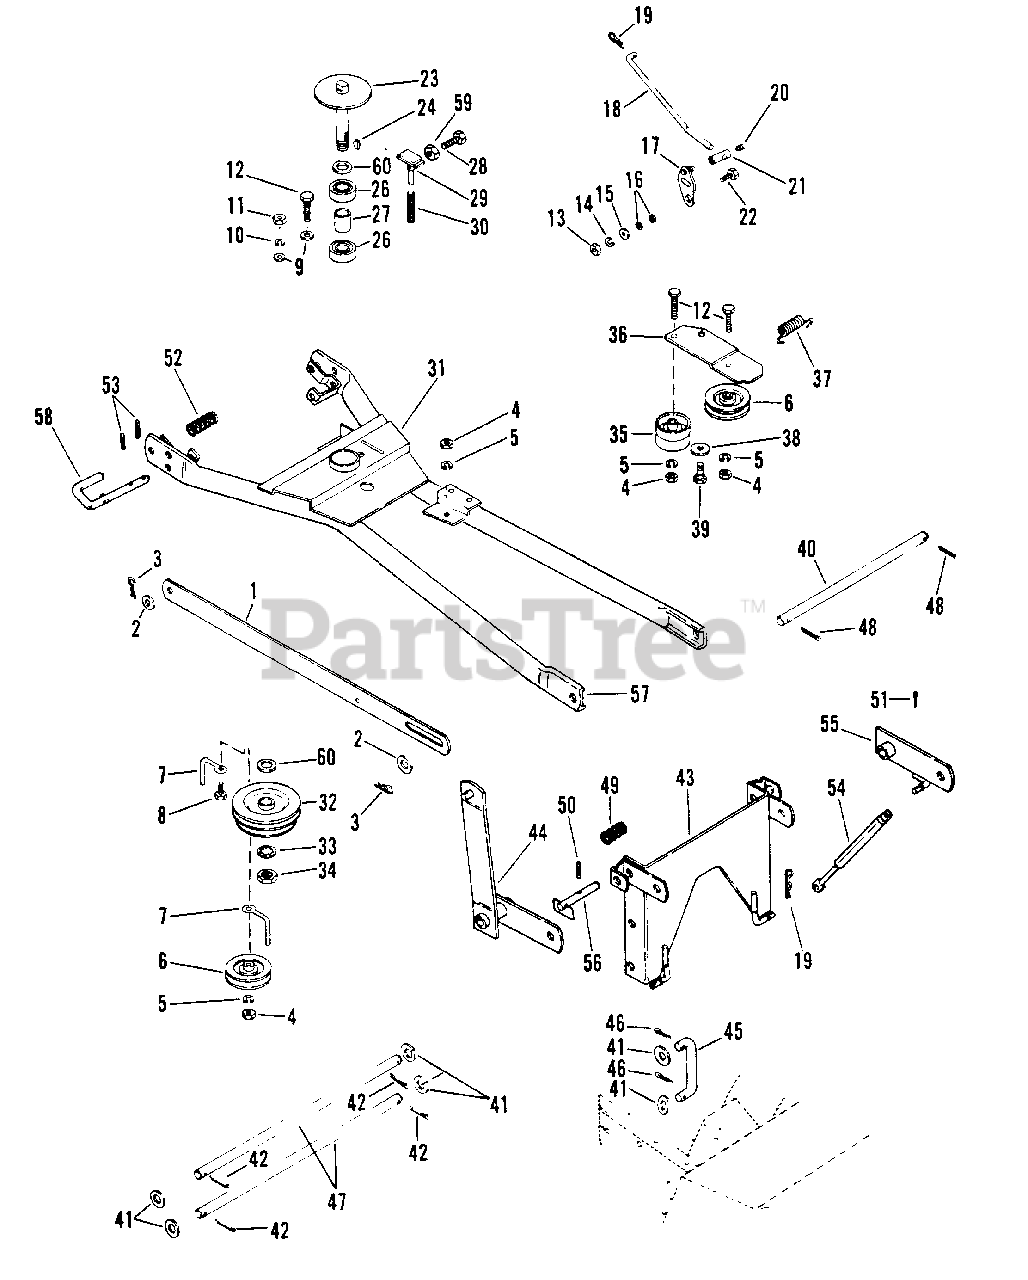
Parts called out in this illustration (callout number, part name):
1	Strap, Lift
2	Washer, Flat .500x1.250x.083
3	Pin, Hair
4	Nut, Hex 3/8-16
5	Washer, Lock 3/8 Reg.
6	Idler, Main
7	Finger, Belt
8	Bolt, Hex 5/16-18x1.00
9	Washer, Flat .406x.812x.065
10	Washer, Lock 5/16 SP
11	Nut, Hex 5/16-18
12	Bolt, Hex 3/8-16x1.75
13	Nut, Hex 1/4-20
14	Washer, Lock
15	Washer, .312x.734x.065
16	Washer, Flat .250x.500x.049
17	Actuator, Brake
18	Rod, Brake
19	Pin, Hair Int. 3/32
20	Set Screw, 5/16-18x.375 HSCP
21	Adaptor, Rod
22	Bolt, Hex 1/4-20x.750
23	Shaft, Spindle
24	Key, Woodruff .187x.75x#9
26	Bearing, Radial
27	Spacer
28	Screw, Cap 10-24x1.25
29	Plunger, Brake
30	Spring, Comp.
31	Housing, Spindle
32	Sheave, Double
33	Lockwasher, Internal 3/4
34	Nut, Jam 3/4-10 Hex
35	Idler, Attachment
36	Arm, Idler
37	Spring, Ext. 3-1/16 Free Length
38	Washer, Flat .515x1.441x.1
39	Bolt, Shoulder
40	Rod, Mount
41	Washer, .656x1.312x.095
42	Pin, Cotter .156x1.50
43	Frame, Pivot
44	Bellcrank, Lift
45	Link, Lift
46	Pin, Cotter .125x1.00
47	Rod, Pivot
48	Pin, Spring .187x1.000
49	Spring
50	Pin, Spring .187x1.500
51	Pin, Cotter .094x1.00
52	Spring, Compression
53	Pin, Spring .125x.750
54	Spring, Gas
55	Lever, Lift
56	Pin, Lock
57	Frame, Carriage
58	Pin, Latch
59	Nut, 10-24 Hex
60	Washer, Flat .770x1.25x.06
